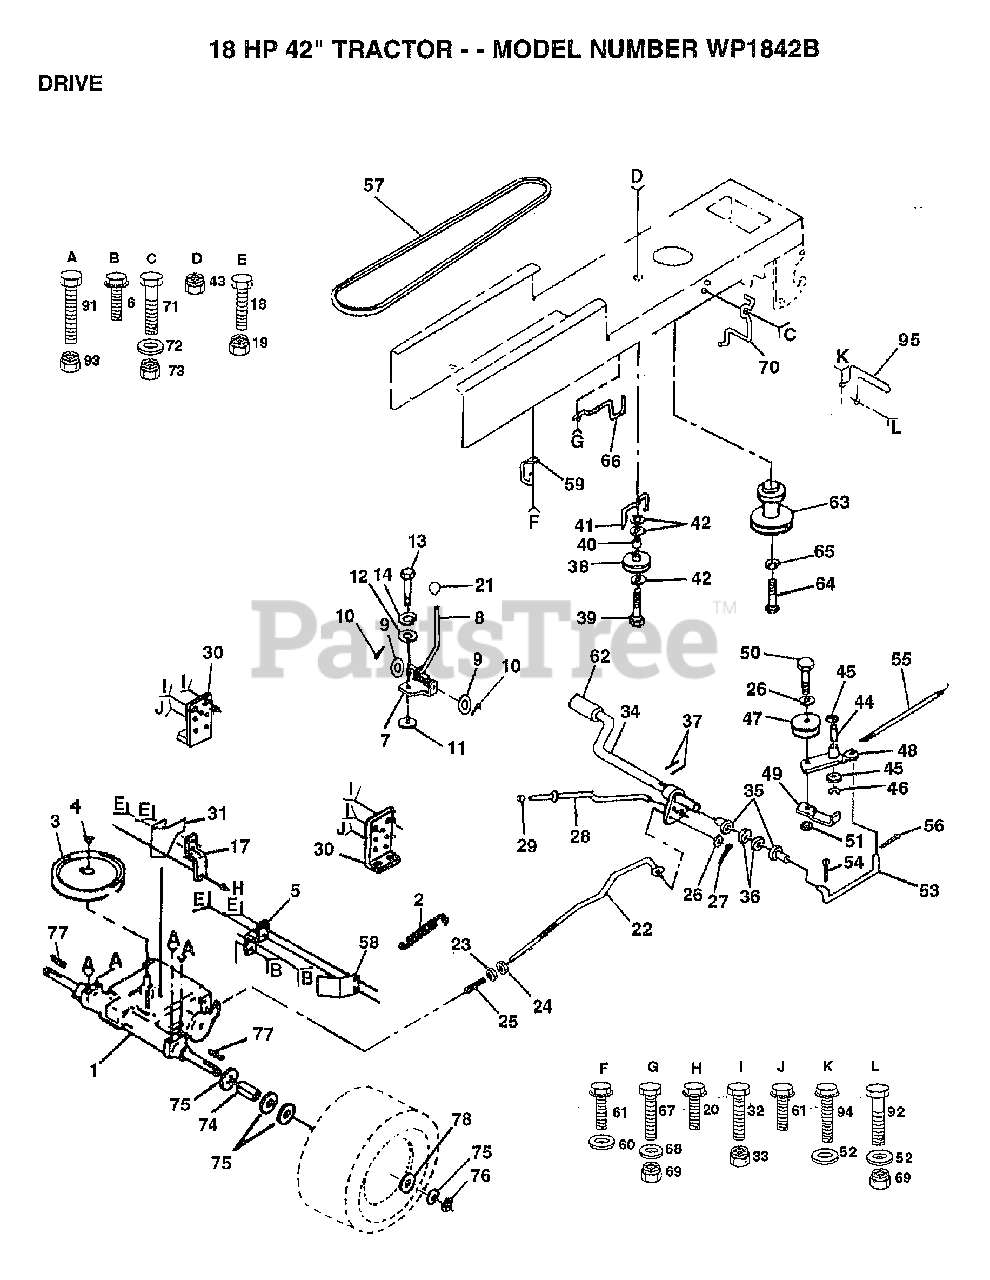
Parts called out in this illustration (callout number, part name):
3	"PULLEY,TRANSAXLE"
5	STRAP TORQUE
6	SCREW
8	SHIFT ROD
9	WASHER
10	PIN COTTER 1/8
11	WASH-SHFT PLT LT
12	WASHER
14	LOCKWASHER
17	STRAP TORQUE
20	SCREW
21	KNOB T (1/2-HOLE)
22	BRAKE ROD
23	NUT
24	NUT
25	SPRING ROD LT
26	WASHER
27	COTTER PIN
28	BRAKE PARK ROD
29	PLUNGER CAP T
30	TRANSAXLE MTG BKT
31	"KEEPER,BELT LH"
32	BOLT
35	NYLON BEARING
36	WASHER LT
38	PULLEY.IDLER.FLAT
39	BOLT
40	SPACER T
41	BELT KEEPER LT
42	WASHER
44	"LY, BEARING"
45	WASHER LT
46	KLIP RING
48	ARM IDLER
49	RETAIN BELT
52	WASHER HYT
53	"LINK, CLUTCH T"
54	COTTER PIN
55	"SPRING, RETURN LT"
56	COTTER PIN
57	BELT-V
58	"KEEPER,BELT RH"
60	WASHER
61	SCREW
62	PEDAL COVER T
64	BOLT
65	LOCKWASHER
66	KEEPER.BELT.ENG.L
67	BOLT
68	WASHER
70	KEEPER BELT ENG
71	BOLT
72	WASHER
74	SPACER LT
75	WASHER
76	E-RING LT
77	SQUARE KEY
78	WASHER
91	BOLT
92	BOLT D
94	SCREW GTV
95	MUFFLER GUARD
